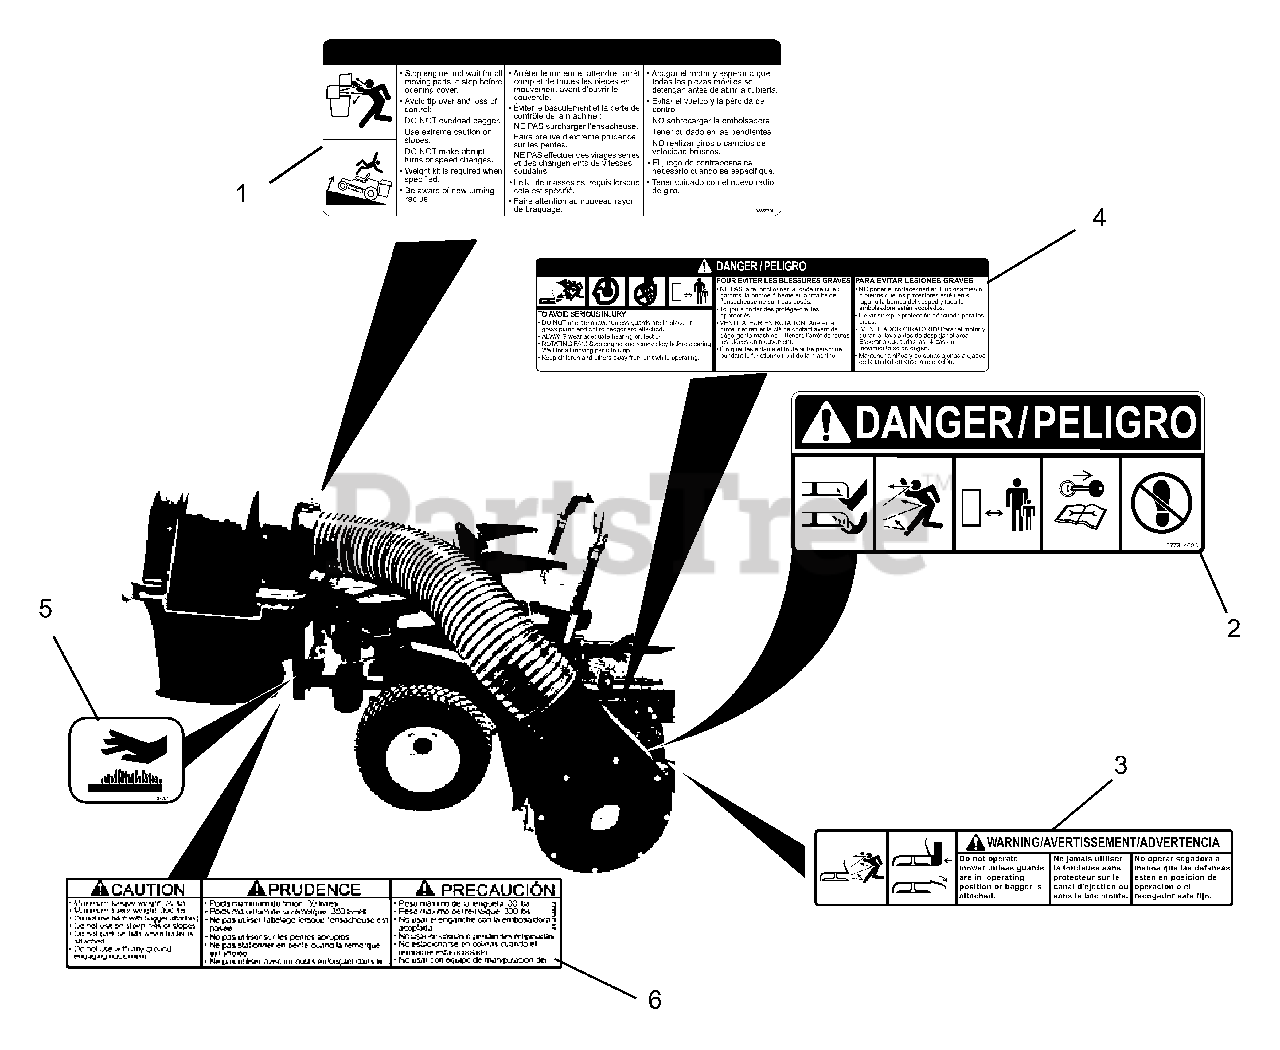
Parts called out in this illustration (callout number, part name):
1	Bagger Cover Decal
2	Mower Pan Danger Decal
3	Warning Decal
4	Grass Pump Caution Decal
5	Decal, Hot Surface
6	Decal, Caution
